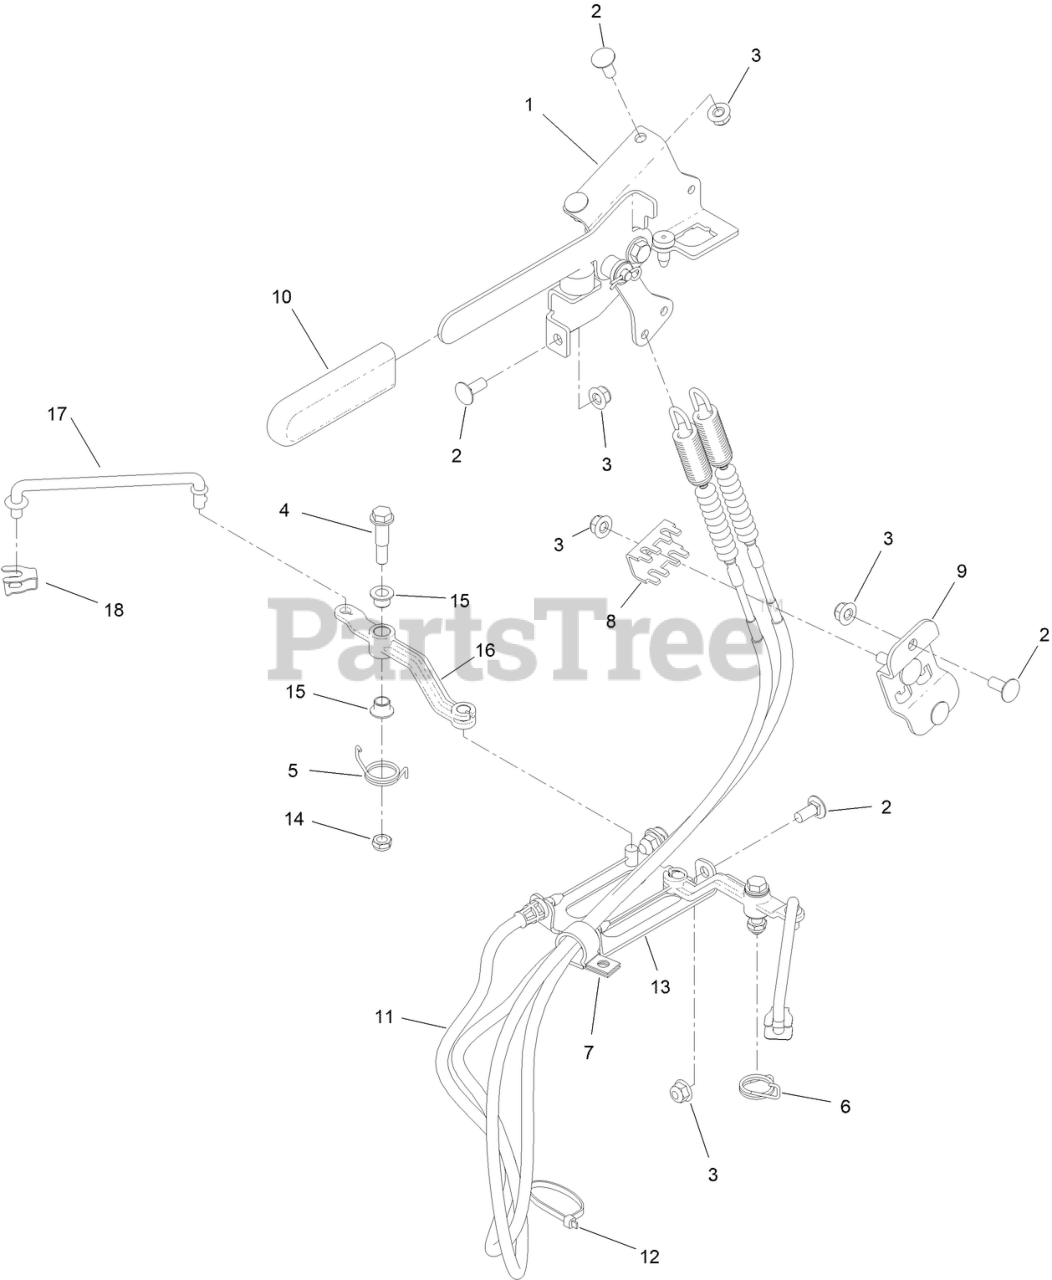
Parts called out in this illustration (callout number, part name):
1	BRAKE HANDLE ASM
2	SCREW-CARR
3	NUT-HF, NI
4	SCREW-SHOULDER
5	SPRING-TORSION
6	SPRING-TORSION
7	R-CLAMP
8	CLAMP-CABLE
9	MOUNT-CABLE, BRAKE
10	GRIP-LEVER
11	CABLE-BRAKE
12	TIE-CABLE
13	BRACKET-CABLE, MOUNT
14	NUT-LOCK, NI
15	BUSHING-FLANGE
16	ARM-BRAKE
17	ROD-BRAKE
18	RETAINER-ROD
